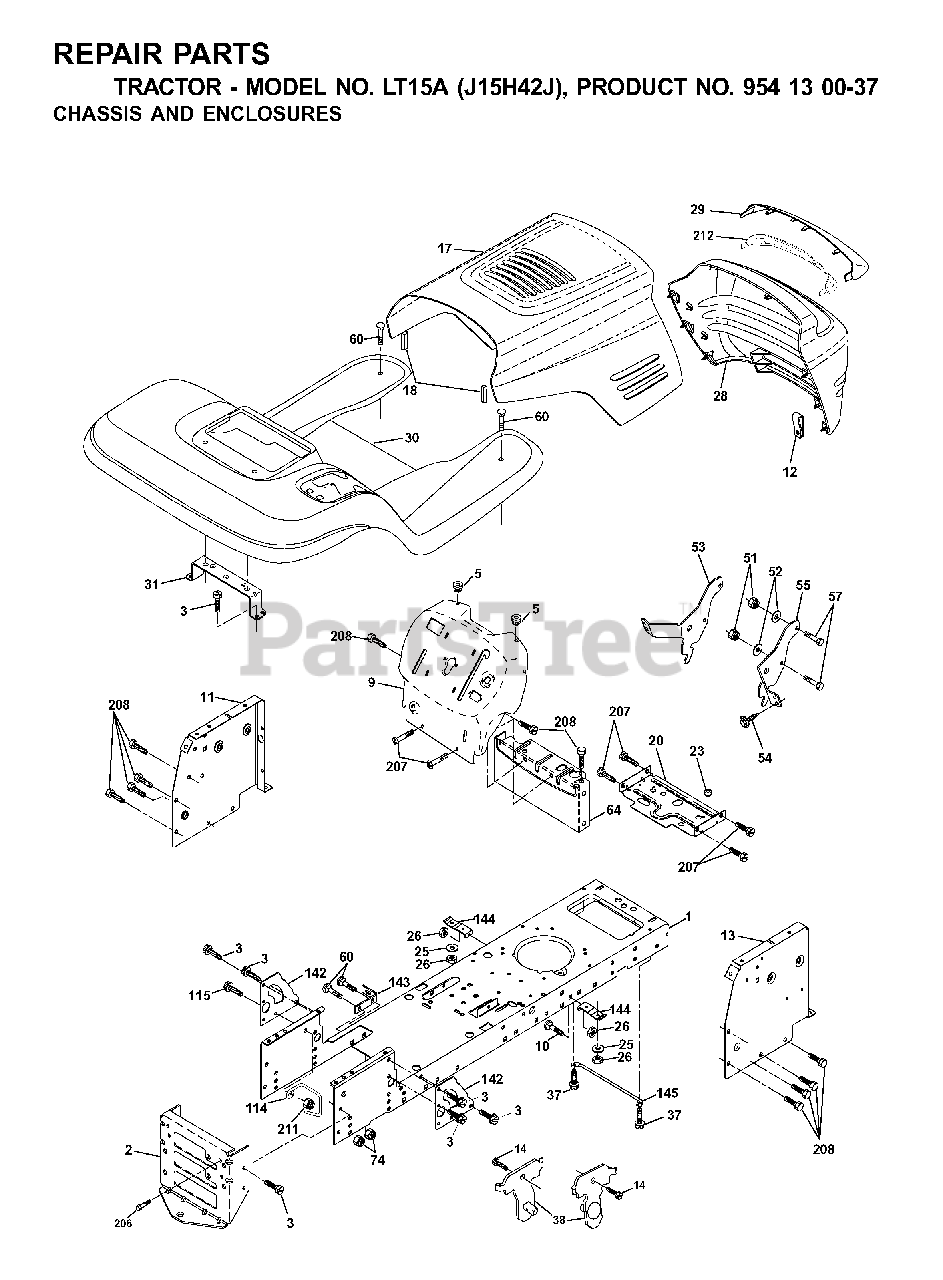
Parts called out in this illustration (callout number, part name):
1	CHASSIS STAMPING
2	DRAWBAR, 12GA
3	SCREW 3/8-16X3/4
5	BUMPER.RUBBER.HOOD
10	BOLT D
11	PANEL DASH LH
13	DASH PANEL RH
18	BUMPER HOOD T
20	PLATE MTG
23	GROMMET T
25	WASHER
26	NUT
38	BRACKET
51	LOCKNUT
57	BOLT
64	DASH LOWER
74	LOCKNUT
142	PLATE
143	BRACKET, SWAY BAR
144	BRACKET FOOTREST
145	ROD PIVOT CHASSIS/HOOD
206	SHOULDER BOLT 5/16-18TT
207	SCREW, 5/16-18 X 1/2
208	SCREW 3/8-16X1/2
